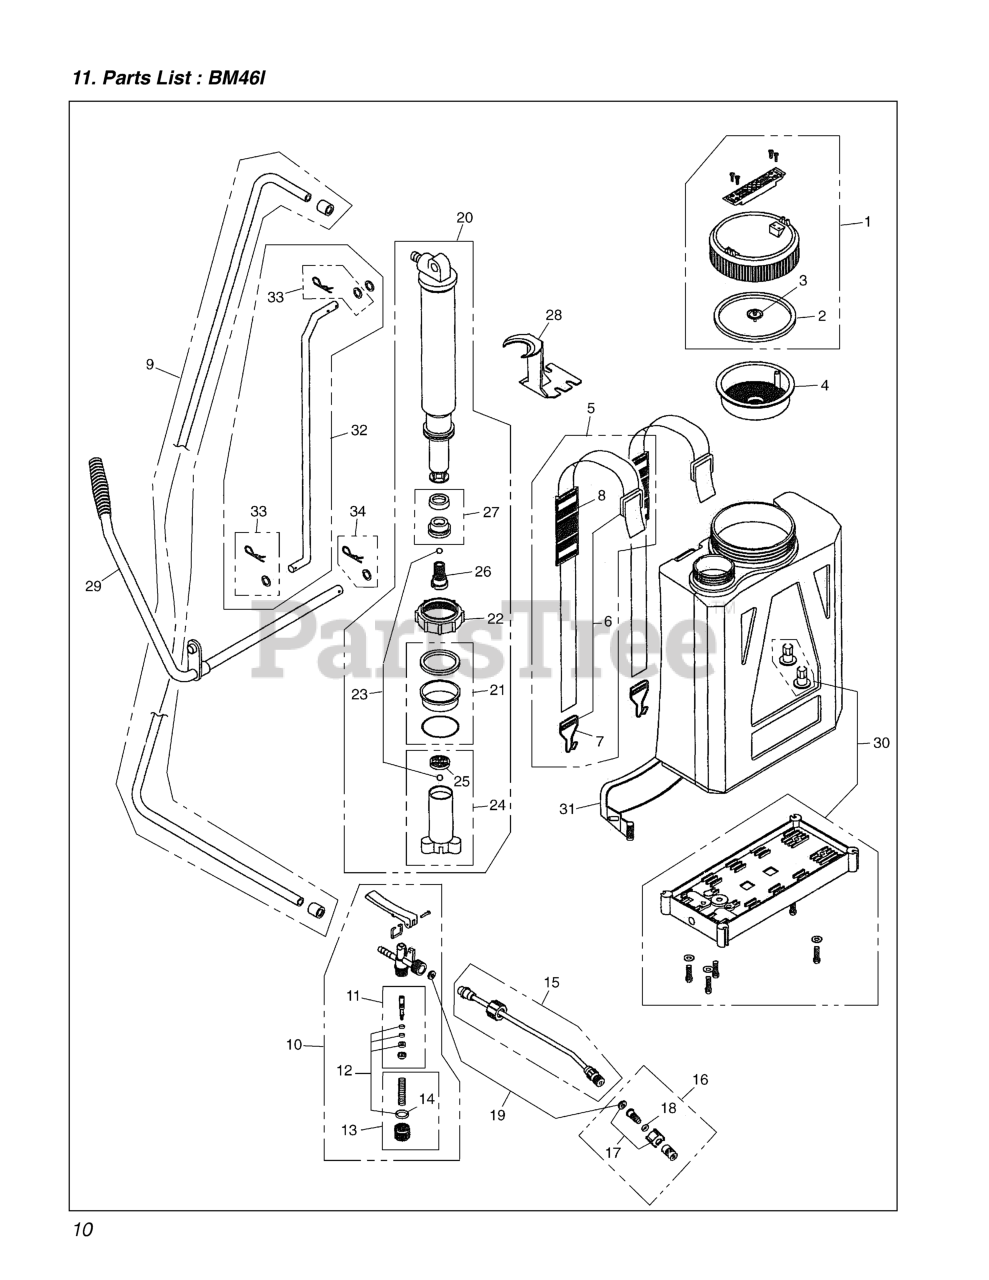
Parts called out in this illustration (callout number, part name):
1	CAP W/HANDLE & CHECK VALVE
2	6
3	CHECK VALVE, CAP
4	TANK STRAINER
5	BELT & CLIP
6	BELT HOOK & BUCKLE
7	HOOK, BELT
8	PAD, SHOULDER
9	HOSE & CLAMPS
10	SPRAY PISTOL, COMP
11	SPINDLE SET
12	O-RING SET, SPINDLE
13	PLUG SET
14	O-RING SET
15	20
16	SPRAY TIP SET
17	NOZZLE HOLDER
18	O-RING, SPRAY TIP
19	WASHER SET, GUN & NOZZLE
20	PUMP ASSY COMPL
21	SEAL & O-RING
22	PUMP UNIT THREADED HOLDER
23	BALL, PLASTIC
24	CYLINDER, COMPL
25	GRATE, CYLINDER
26	PISTON HOLDER
27	PISTON CUP & PLASTIC CAP
28	AGITATOR
29	PUMP HANDLE W/PLASTIC GRIP
30	BASE ASSY, COMPL
31	HIP SUPPORT
32	PUMP LEVER W/LOCKING PIN
33	LOCKING PINS-PUMP HANDLE SM
34	LOCKING PIN-PUMP HANDLE LG
